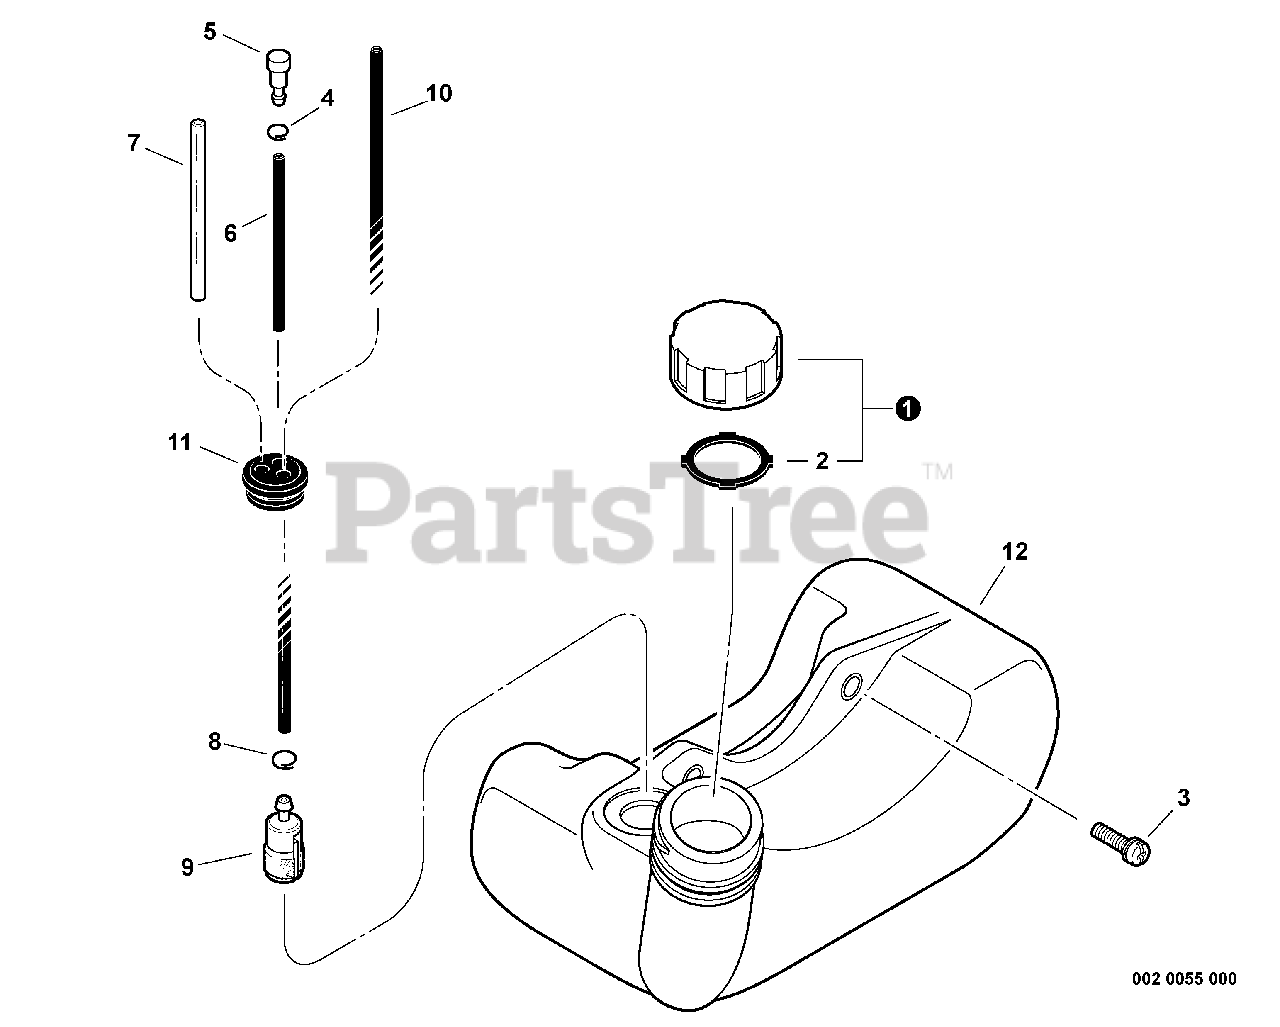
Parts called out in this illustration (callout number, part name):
1	CAP ASSY, FUEL
2	GASKET, FUEL CAP
3	SCREW 5×16
5	VENT ASSY
6	PIPE, FUEL 3x-5x-70 BLACK
7	PIPE, FUEL RETURN 3×6×70
8	CLIP 6 MM
9	FILTER, FUEL
10	PIPE, FUEL 3x-5x-180
11	GROMMET, FUEL
12	TANK, FUEL
